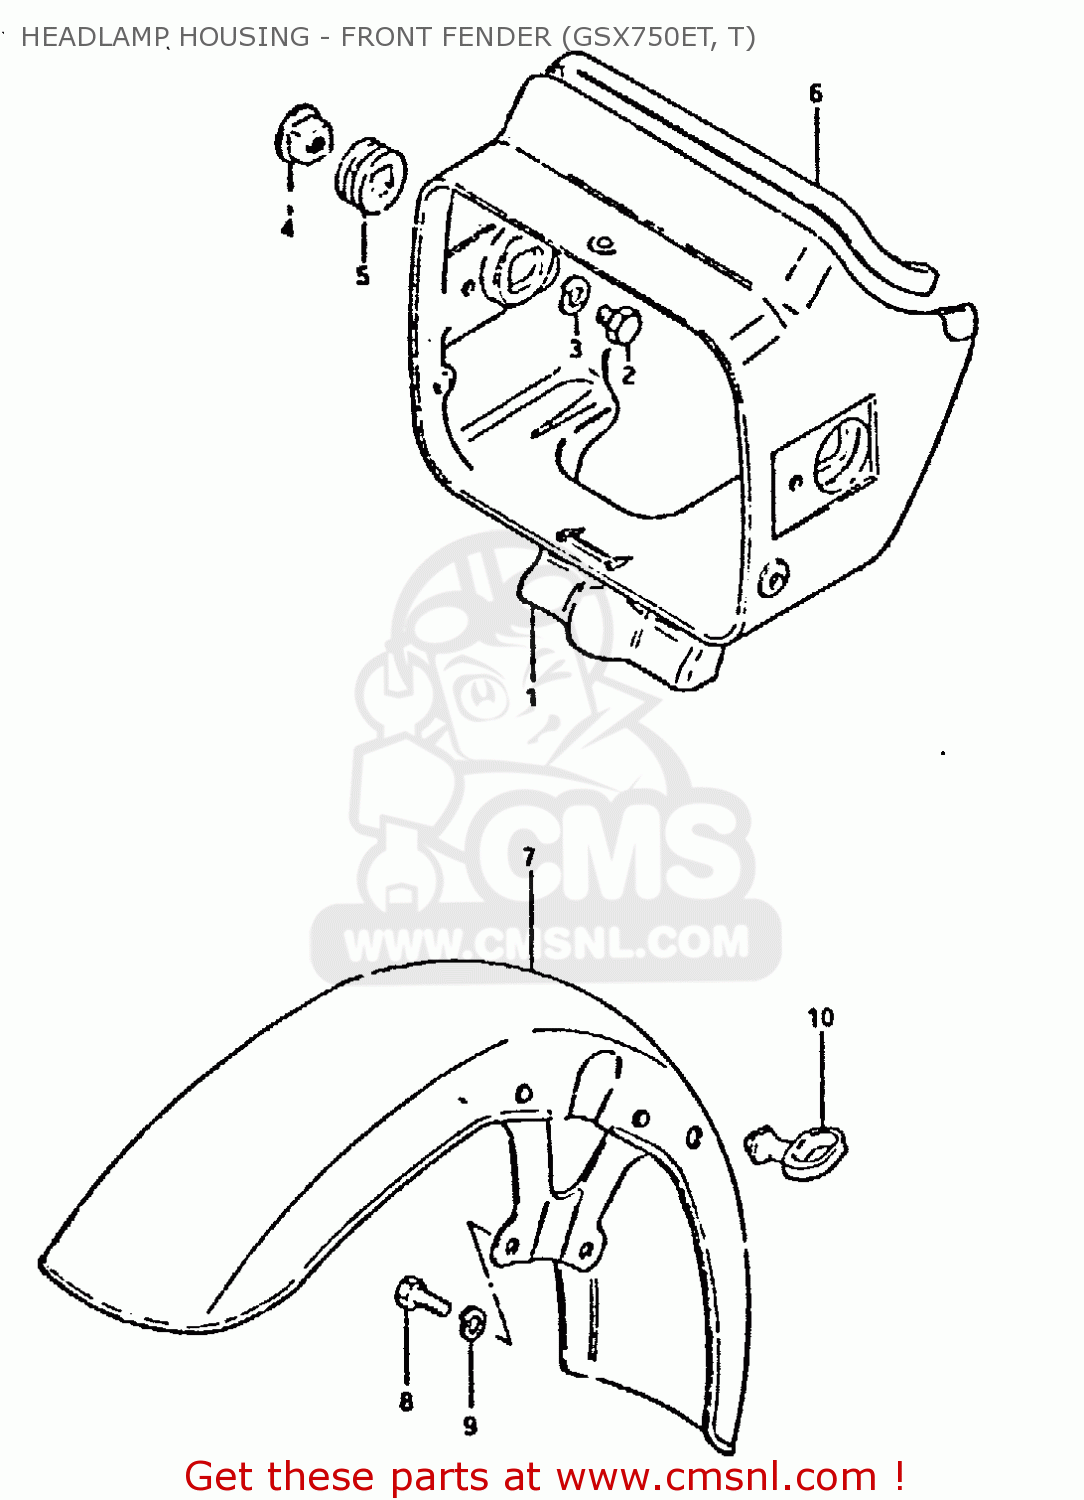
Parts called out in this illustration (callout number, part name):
1	HOUSING, HEADLAMP
2	BOLT
3	LOCK WASHER
4	SPACER,HEADLAMP HOUSING
5	CUSHION,HEADLAMP HOUSING
6	MOLDING,HEADLAMP HOUSING
7	FENDER, FRONT
8	BOLT
9	LOCK WASHER
10	GUIDE,CABLE
